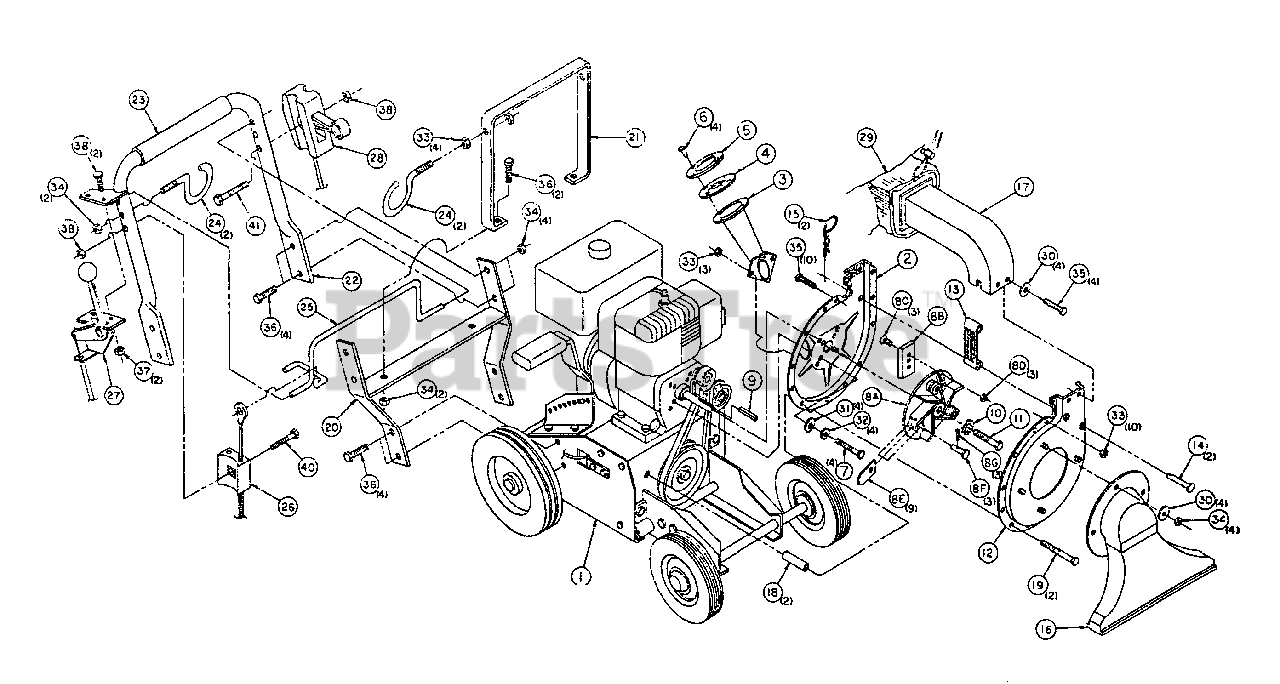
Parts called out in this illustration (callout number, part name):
1	Drive Train Assembly
2	Engine Housing
3	Chipper Tube Weldment
4	Chipper Chute Cover
5	Mounting Range
6	3/16" x .402 Pop Rivet
7	5/16-24 x 2-1/4" HHCS
8A	Shredder Plate Weldment
8C	5/16-18 x 1" Flat Hd. Soc. Cap Screw
8D	5/16-18 Nylok Locknut
8F	Hammer Rod
8G	1/8" Dia. x 1" Lg. Roll Pin
9	1/4" x 1/4" Shaft Key
10	3/8" Med. Split Lockwasher
11	3/8-24 x 2-1/4" HHCS, GR8, Blk.
12	Inlet Housing
13	Shredder Screen
14	Screen Rod
15	1/8" Hair Cotter Pin
17	Discharge Tube
18	Lower Housing Mounting Spacer
19	5/16-18 x 5-1/2" HHCS
20	Lower Handle Weldment
21	Bag Hanger Frame
22	Upper Handle Bar
23	Handle Bar Grip
24	Bag Hanger Eyebolt
26	Clutch Cable Assembly
27	Shift Cable
28	Throttle Cable
29	Collection Bag
30	5/16 Fender Washer
31	5/16" Flatwasher, Pltd.
32	5/18" Med. Split Lockwasher, Pltd.
33	5/16-18 Whiz Locknut, Pltd.
34	5/16-18 Nylok Locknut, Pltd.
35	5/16-18 x 5/8" HHCS, GR5
36	5/16-18 x 1, HHCS
37	1/4-20 Whiz Locknut, Pltd.
38	1/4-20 Nylok Locknut, Pltd.
40	1/4-20 x 1-3/4" HHCS
41	1/4-20 x 2-1/4" HHCS
